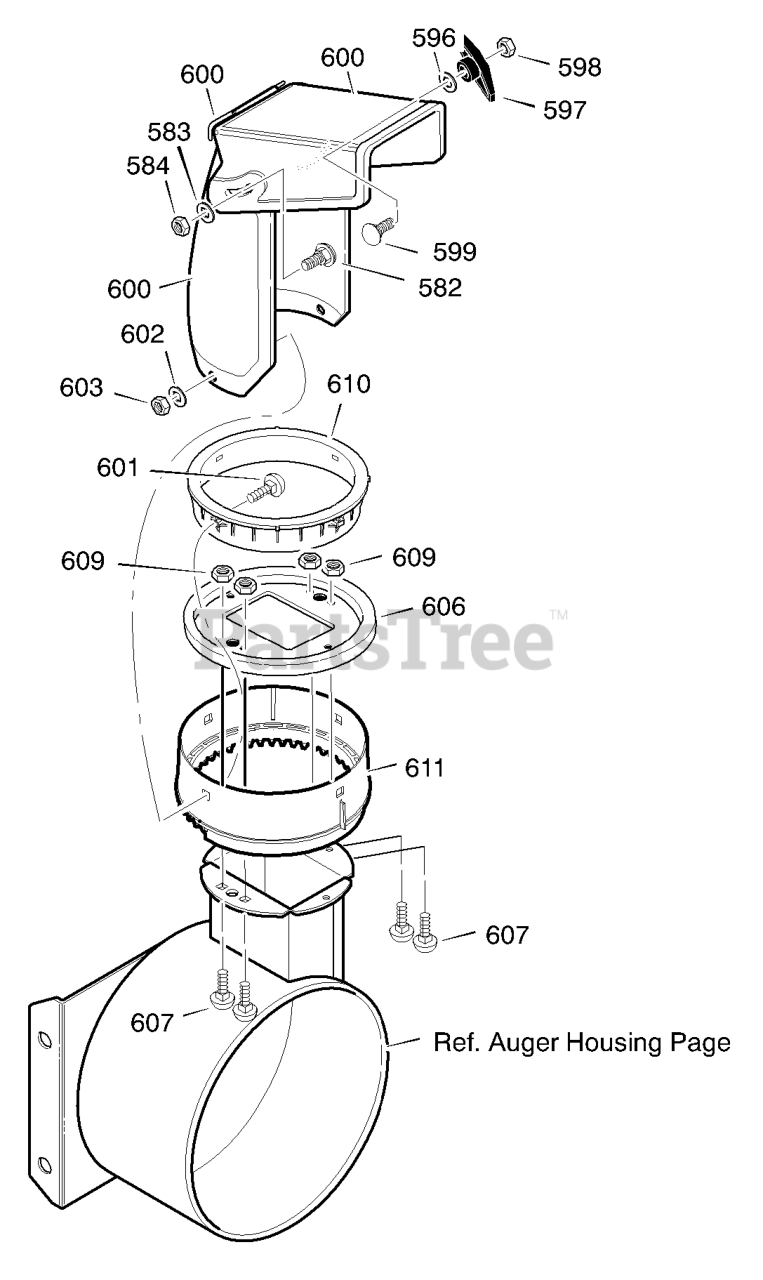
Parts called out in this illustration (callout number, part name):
582	SCREW, 5/16-18 x 1.00
583	WASHER, FLAT
584	NUT, 5/16-18
596	WASHER
597	KNOB, T 3.00
598	NUT, 5/16-18
599	BOLT, 5/16-18X1.00
600	CHUTE ASSEMBLY
601	BOLT, 5/16-18 X1.50
602	WASHER, FLAT
603	NUT, 5/16-18
606	CHUTE COLLAR
607	SCREW, 1/4-20 X 0.75
609	NUT, 1/4-20 HEX NYLOCK
610	RETAINER RING INNER
611	RETAINER RING OUTER
